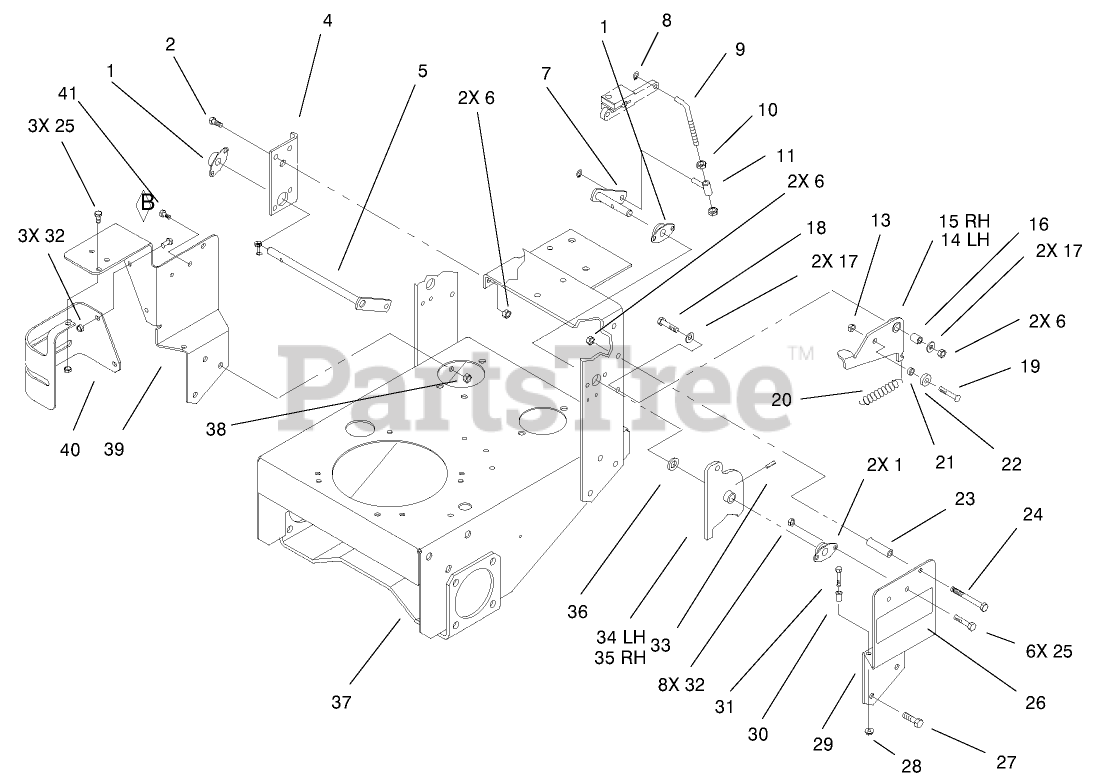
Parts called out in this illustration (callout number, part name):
1	SIDE FLANGE BEARING ASM
2	SCREW-HH
4	BRACKET-BUSHING
5	LEVER-PIVOT, RH
6	NUT-LOCK, NI
7	LEVER-PIVOT, LH
8	RING-GRIP
9	ROD-LINK
10	NUT-JAM
11	SLEEVE
13	NUT-LOCK, NI
14	ARM-DETENT, LH
15	ARM-DETENT, RH
16	BUSHING-ARM, DETENT
17	WASHER-PLAIN
18	SCREW-HH
19	SCREW-HSBH
20	SPRING-DETENT
21	SPACER-BEARING
22	BEARING-BALL
23	STOP-REVERSE
24	SCREW-HH
25	SCREW-HH
26	DECAL-HYDRO
27	SCREW-HH
28	NUT-LOCK, HHF
29	BRACKET-PIVOT, LH
30	SPACER-TUBULAR
31	SCREW-HH
32	NUT-LOCK, NI
33	PIN-ROLL, SLOTTED
34	ARM-PIVOT, LH
35	ARM-PIVOT, RH
36	WASHER-THRUST
37	FRAME WA
38	NUT-LOCK, NI
39	BRACKET-PIVOT, RH
40	GUARD-FILTER
41	SCREW-HH
